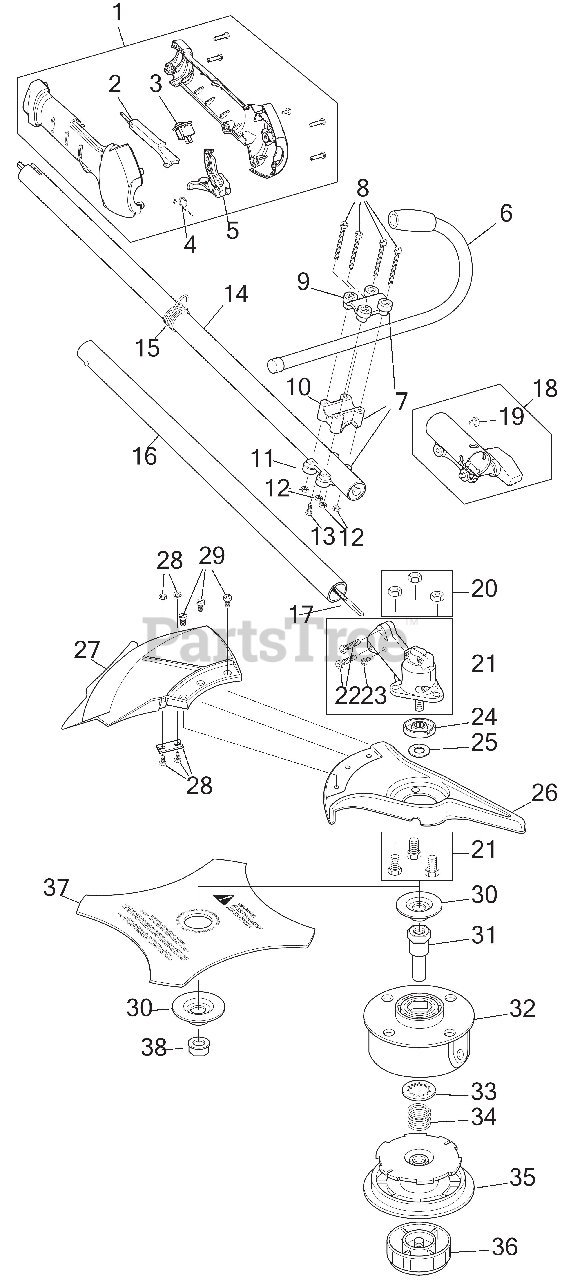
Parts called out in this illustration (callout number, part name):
1	THROTTLE GRIP ASSEMBLY
2	THROTTLE LVR LKOUT
3	SW, MOMENTARY ON/O
4	SPRING TRIG
5	THROTTLE TRIGGER
6	ASSEMBLYMY, J-HANDLE W/
7	HANDLE BRACKET ASSEMBLY
8	SCREW-CLAMP
9	CLAMP-HANDLE UPPER
10	CLAMP-HANDLE MIDDLE
11	CLAMP-HANDLE LOWER
12	NUT-CLAMP
13	SCREW, 8-32 x .312 P
14	UPPER DRIVE SHAFT HOUSING ASSEMBLY
15	CLAMP-SHOULDER STR
16	ASSEMBLY, LOWER DRIVE S
17	LOWERIBLE DRIVE SHAFT
18	SPLIT BOOM CPLR
19	SCREW, 10-32X.250 TA
20	SCREW SET-GUARD MT
21	GEARBOX ASSEMBLY
22	SCREW #
23	SCREW, 8-32 x .312 P
24	SPACER-GEARBOX
25	PALNUT:3/8" DIAMET
26	SHIELD-BLADE CAST
27	SHIELD ASSEMBLY WITH BLADE
28	BLADE ASSEMBLY
29	SCREW-GUARD MTG PK
30	WASHER-BLADE CLAMP BRUSH CUT
31	SHAFT-SPOOL
32	SPOOL ASSEMBLY-OUTER
33	RETAINER .968 OD
34	SPRING-SPOOL
35	REEL-INNER SPOOL 3000 STRG TRM
36	KNOB ASSEMBLY-BUMP 3000 STRG TRM
37	BLADE 4-TOOTH
38	BLADE LOCK NUT
